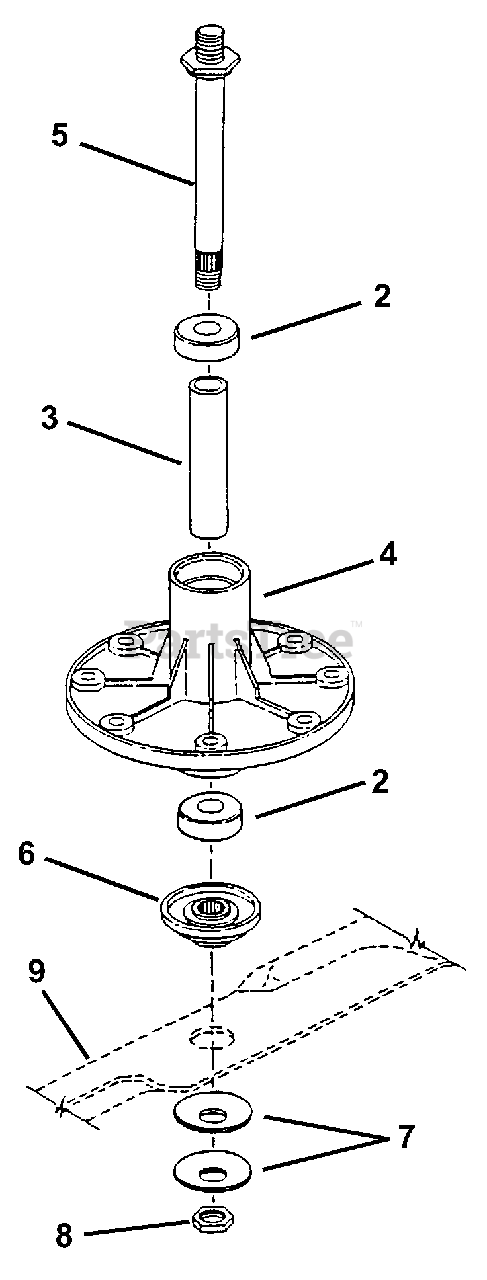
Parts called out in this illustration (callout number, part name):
2	BEARING, Spindle
3	SPACER, Spindle Housing
4	HOUSING, Spindle
5	SPINDLE (7.02" overall length)
6	SPACER, Blade
7	WASHER, Belleville, 19/32"
8	NUT, 9/16-18 Hex Jam
9	BLADE, 19.64"
